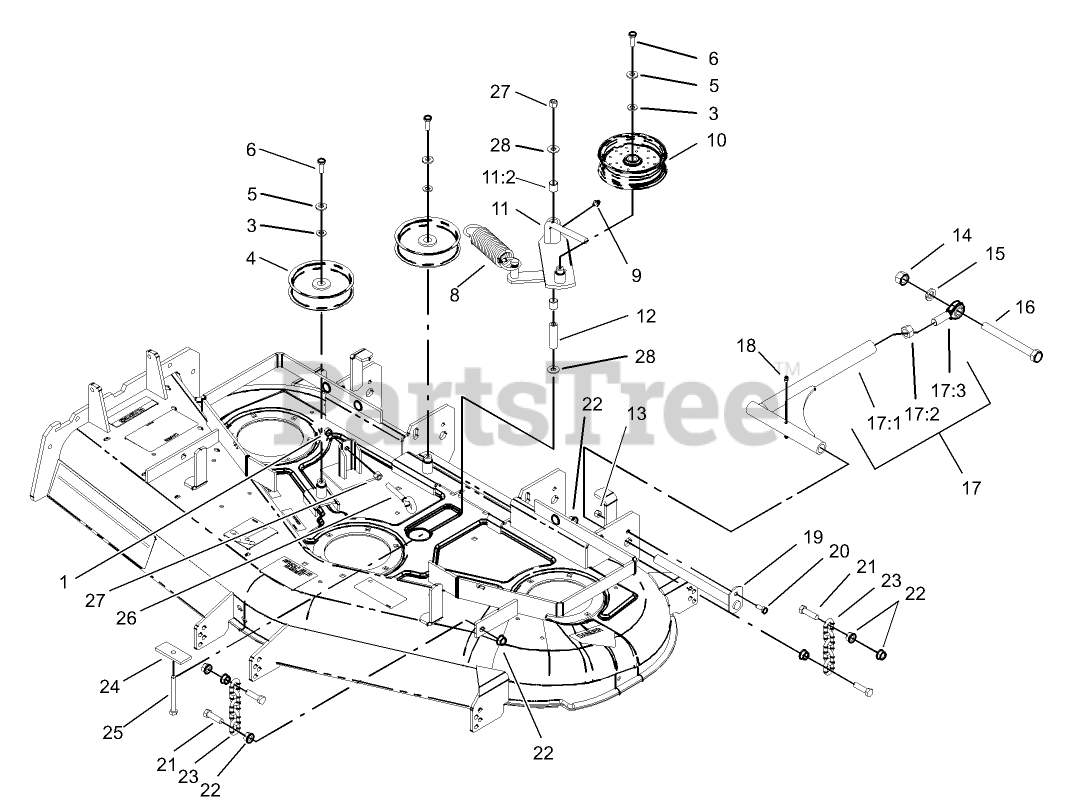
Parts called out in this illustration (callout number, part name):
1	NUT-HEX
3	WASHER-FLAT
4	PULLEY-IDLER
5	WASHER-BELLEVILLE
6	SCREW-HH
8	Spring-Extension
9	FITTING-GREASE, 90 DEG
10	PULLEY-IDLER
11	IDLER ARM ASM
11:2	SLEEVE-BEARING
12	BUSHING-PIVOT, IDLER
13	NUT-LOCK, NI
14	NUT-HEX
15	WASHER-LOCK
17	STRUT ASM
17:1	STRUT
17:2	NUT-HEX
17:3	BALLJOINT-SPHERICAL
18	FITTING-GREASE
19	PIN-STRUT
20	SCREW-HH
21	SCREW-CAP, HH
22	NUT-HF
23	CHAIN-LIFT, DECK
24	PLATE-RETAINER, BOLT
25	SCREW-HH
26	BOLT-EYE
27	NUT-LOCK, NI
28	WASHER-HARDENED
